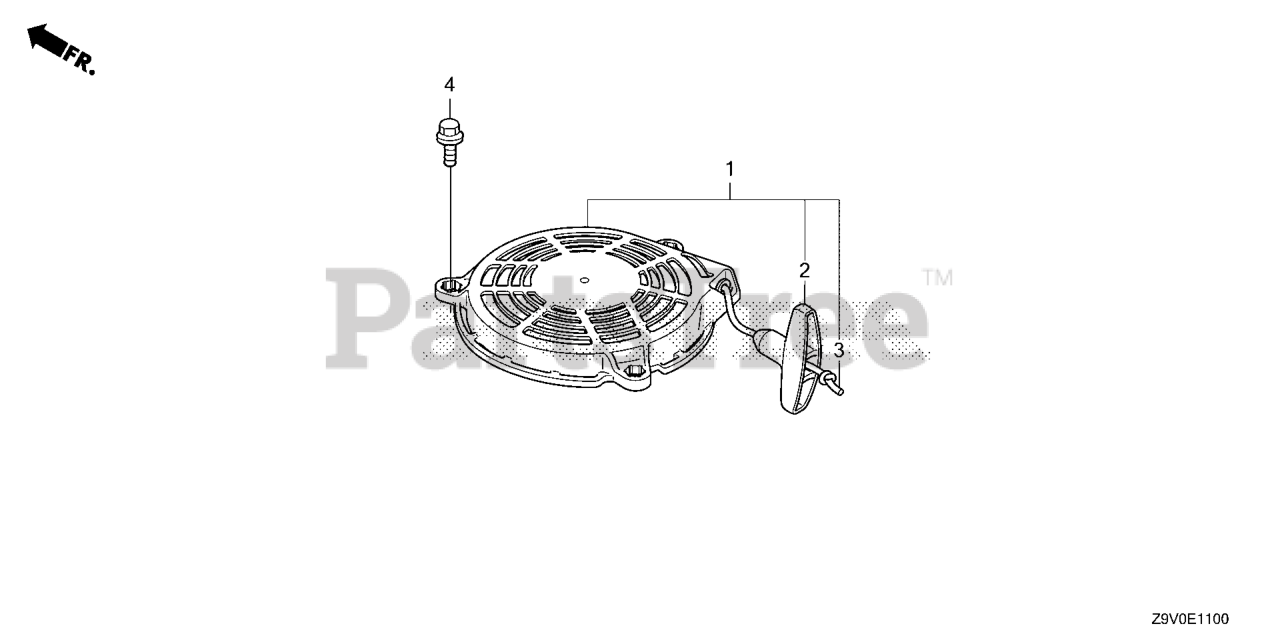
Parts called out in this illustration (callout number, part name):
1	STARTER, RECOIL
2	KNOB, RECOIL STARTER
3	ROPE, RECOIL STARTER (LONG TYPE)
4	BOLT, FLANGE (6X14)
